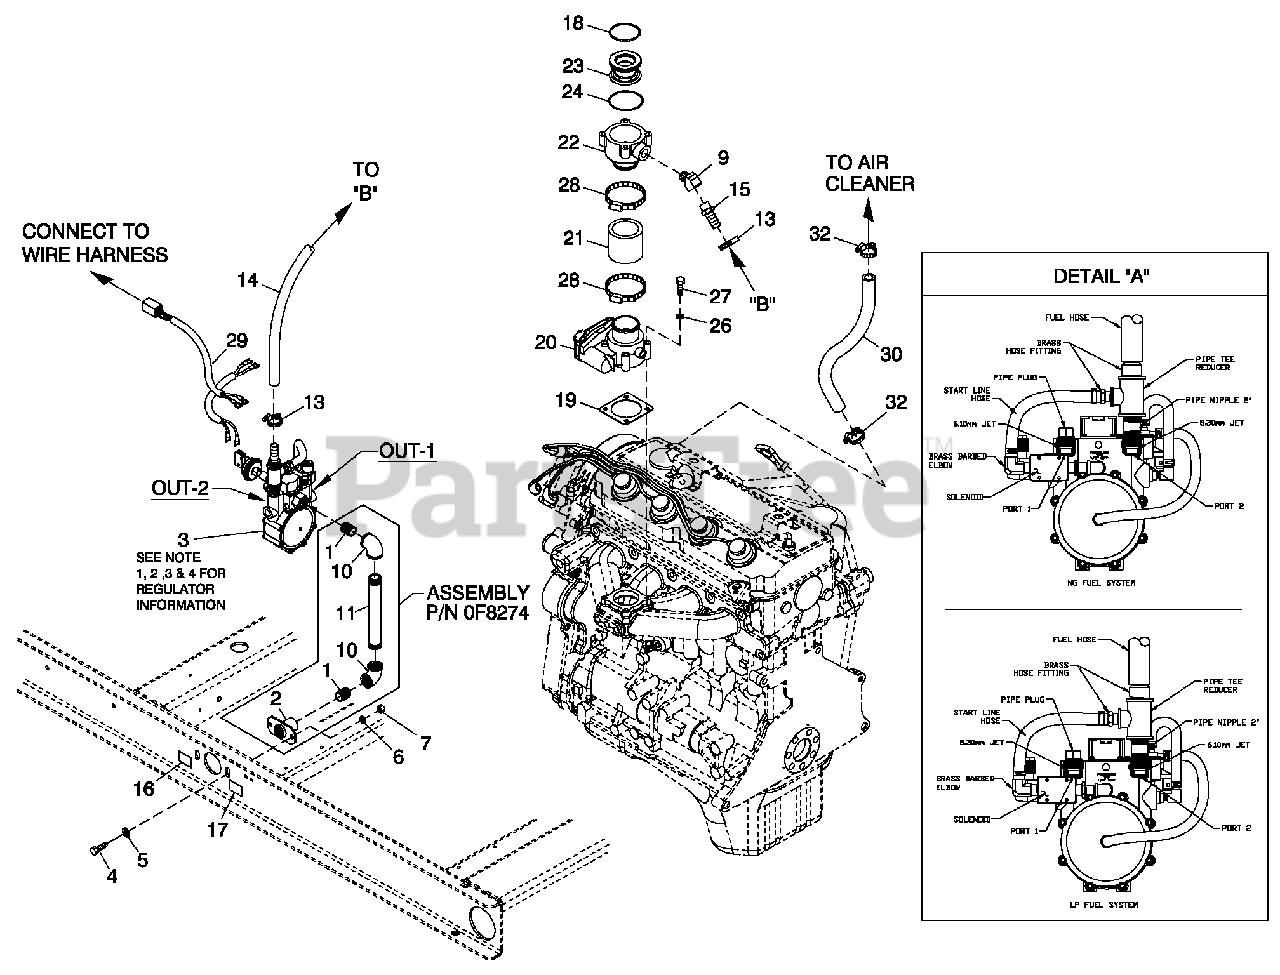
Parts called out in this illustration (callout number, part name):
1	NIPPLE CLOSE 3/4X1.375
2	FLANGE FUEL lNLET
3	REGULATOR ASSY 2.4L (25KW)
4	SCREW HHC M8-1.25X 20 G8.8
5	WASHER FLAT 5/16-M8 ZINC
6	WASHER LOCK M8-5/16
7	NUT HEX M8-1.25 G8 CLEAR ZINC
9	STREET EL 45D 1/2 NPT BRASS
10	ELBOW 90D 3/4 NPT
11	NIPPLE PIPE 3/4 NPT X 7
13	CLAMP HOSE #10 .56-1.06
14	HOSE 3/4 ID SAE-30R2 (18"LG)
15	BARBED STR 1/2 NPT X 3/4
16	DECALl NLET PRESSURE
17	DECAL FUEL lNLET NG (NATURAL GAS APPLICATION)
18	O-RINGl45.63 ID X 2.62 WIDTH
19	GASKET BOSCH 32
20	ACTUATOR BOSCH 40 GOVERNOR (45KW)
21	HOSE COOL 2 IN ID 20R4 (45KW)
22	MIXER ACTUATOR 32MM MACHINED (25KW)
23	VENTURl THROTTLE 26MM (35 & 45KW)
24	O-RING 47.625 ID X 2.38 WIDTH
26	WASHER LOCK M6-1/4
27	SCREW SHC M6-1.0 X 45 G12.9
28	CLAMP HOSEl#28 1.32-2.25
29	HARNESS CPL FUEL JUMPER
30	HOSE 3/8 ID SINGLE BRAID (18"LG)
32	CLAMP HOSE #10 .56-1.06
